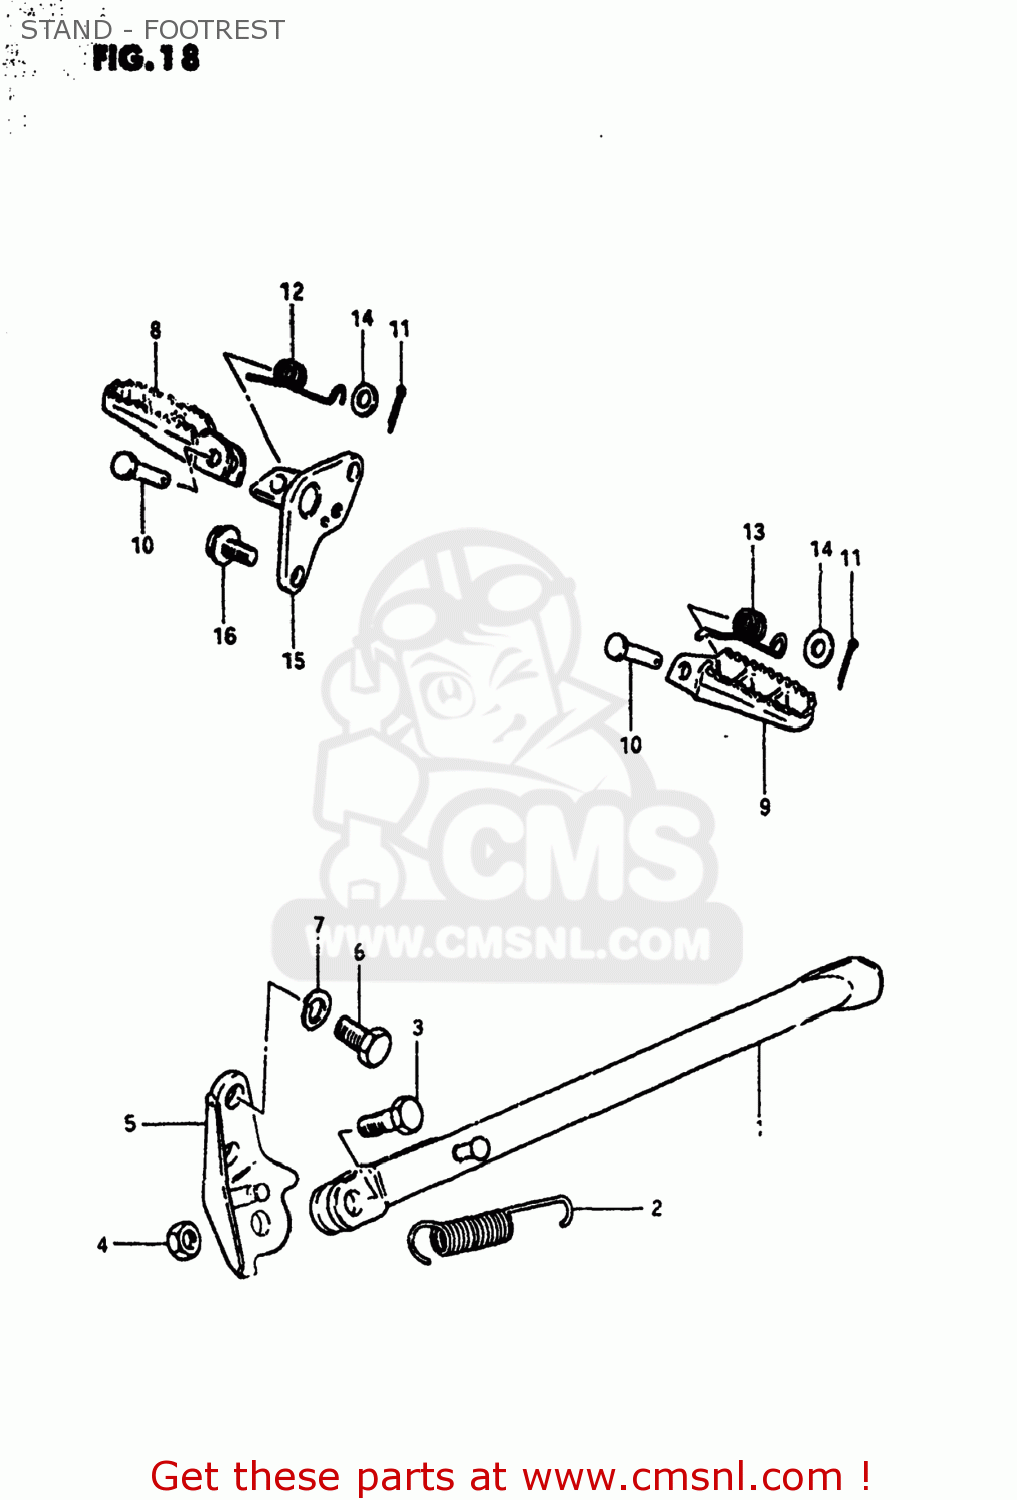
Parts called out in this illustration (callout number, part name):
1	STAND,PROP
2	SPRING
3	BOLT(10X30)
4	NUT
5	BRACKET,PROP STAND
6	BOLT(10X19)
7	LOCK WASHER
8	RUBBER,FRONT FOOTREST
9	FOOTREST
10	PIN
11	PIN 20X20
12	SPRING
13	SPRING
14	WASHER
15	HOLDER,FRONT FOOTREST,RIGHT
16	BOLT(10X20)
